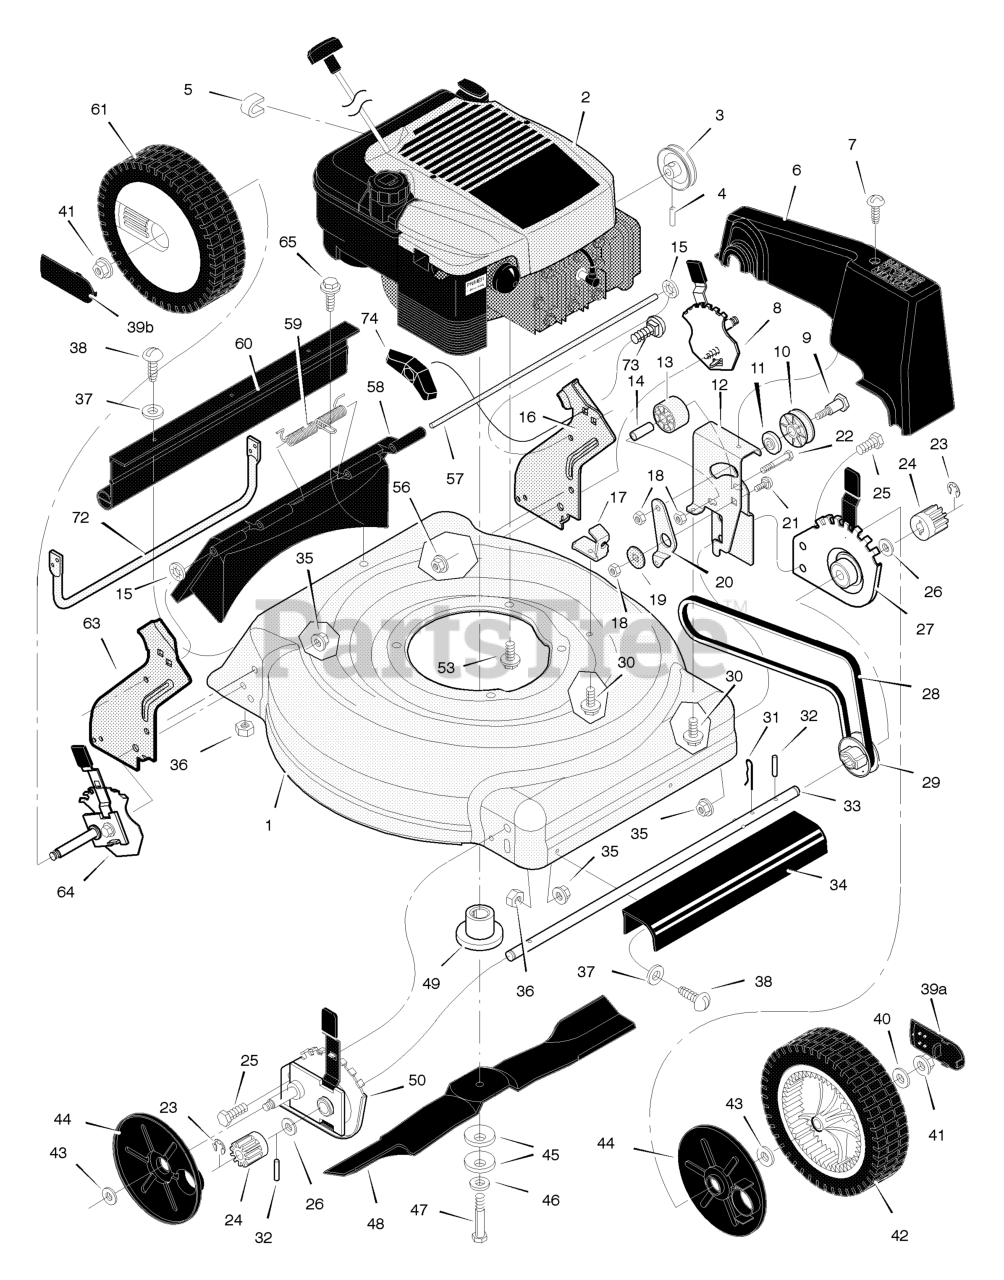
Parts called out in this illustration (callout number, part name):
1	Housing
2	Engine *
3	Pulley, Engine
4	Pin, Spring
6	Cover, Belt (Gray)
8	Adjuster, Left Height
9	Bolt, Shoulder
10	Idler, V
11	Spacer, Idler
12	Bracket, Idler Support
13	Pulley, Rear Idler
14	Bearing
15	Push Retainer
16	Bracket, Left Handle
17	Bracket, Cable
18	Nut, Hex
19	Spacer - Idler Arm
20	Arm, Idler
21	Bolt, Carriage
22	Bolt, Shoulder
24	Gear, Pinion
25	Bolt
27	Adjuster, Left Frt. Height
29	Pulley, Axle
31	Pin, Hair
32	Pin, Spring
34	Cover, Axle (Gray)
35	Nut, Flange
36	Nut, Hex
39A	Cap, Hub
39B	Cap, Hub
40	Washer
41	Nut, Flange
42	Wheel, Drive
44	Cover, Dust
45	Washer, Belleville
49	Adapter, Blade
50	Adjuster, Right Frt. Height
53	Bolt, Engine
56	Nut, Flange
57	Rod, Pivot
58	Door, Rear (Gray)
59	Spring
60	Deflector, Rear
61	Wheel, Rear
63	Bracket, Right Handle
64	Adjuster, Right Height
72	Guard, Rear
73	Bolt, Carriage
74	Knob, Wing
